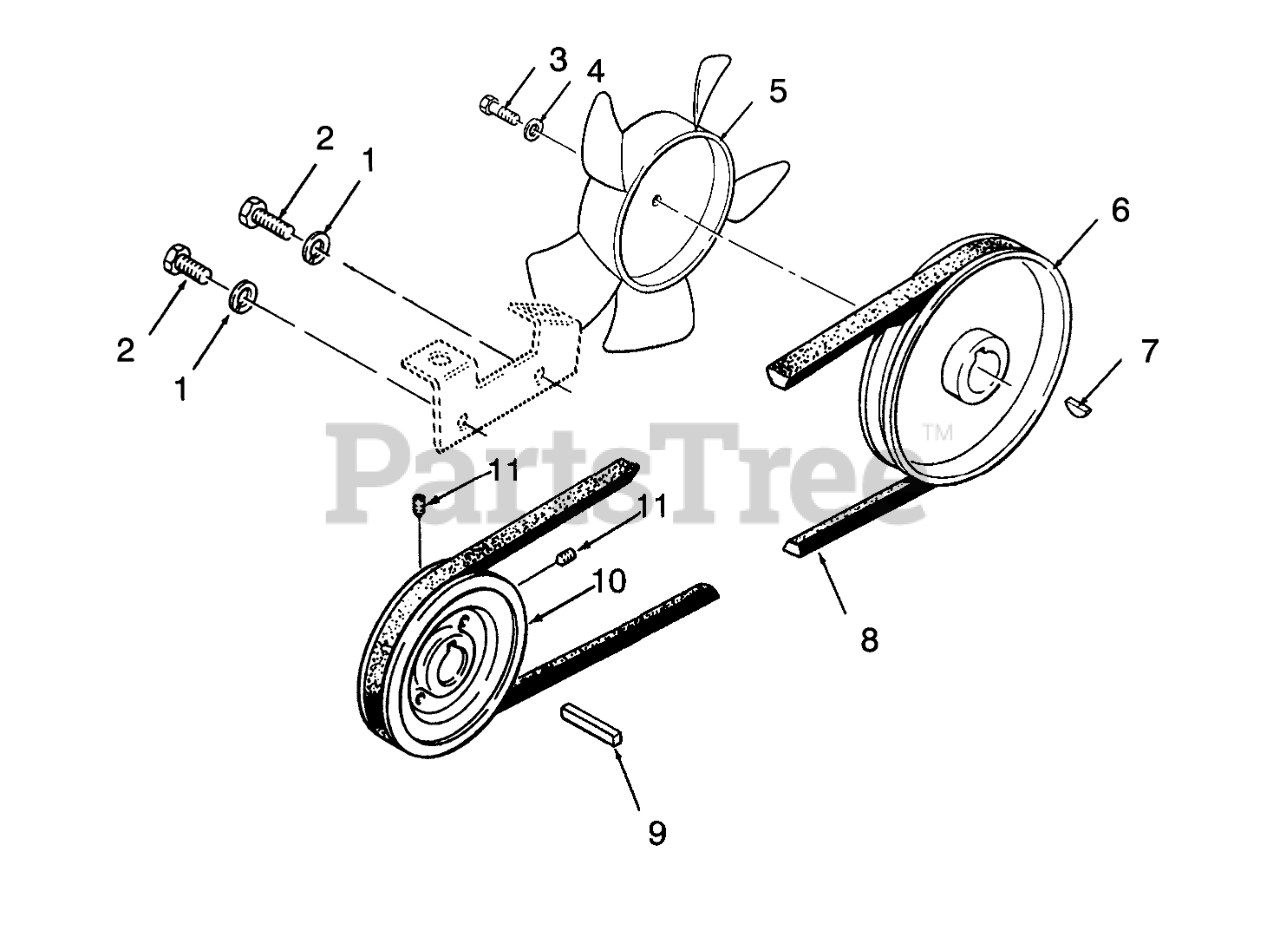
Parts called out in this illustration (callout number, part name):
1	WASHER-LOCK
2	SCREW-HH
3	SCREW-HH
4	WASHER
5	NYLON FAN-L-CW
6	PULLEY
7	KEY-HI PRO
8	BELT-V
10	PULLEY
11	SCREW-SET, HSH
